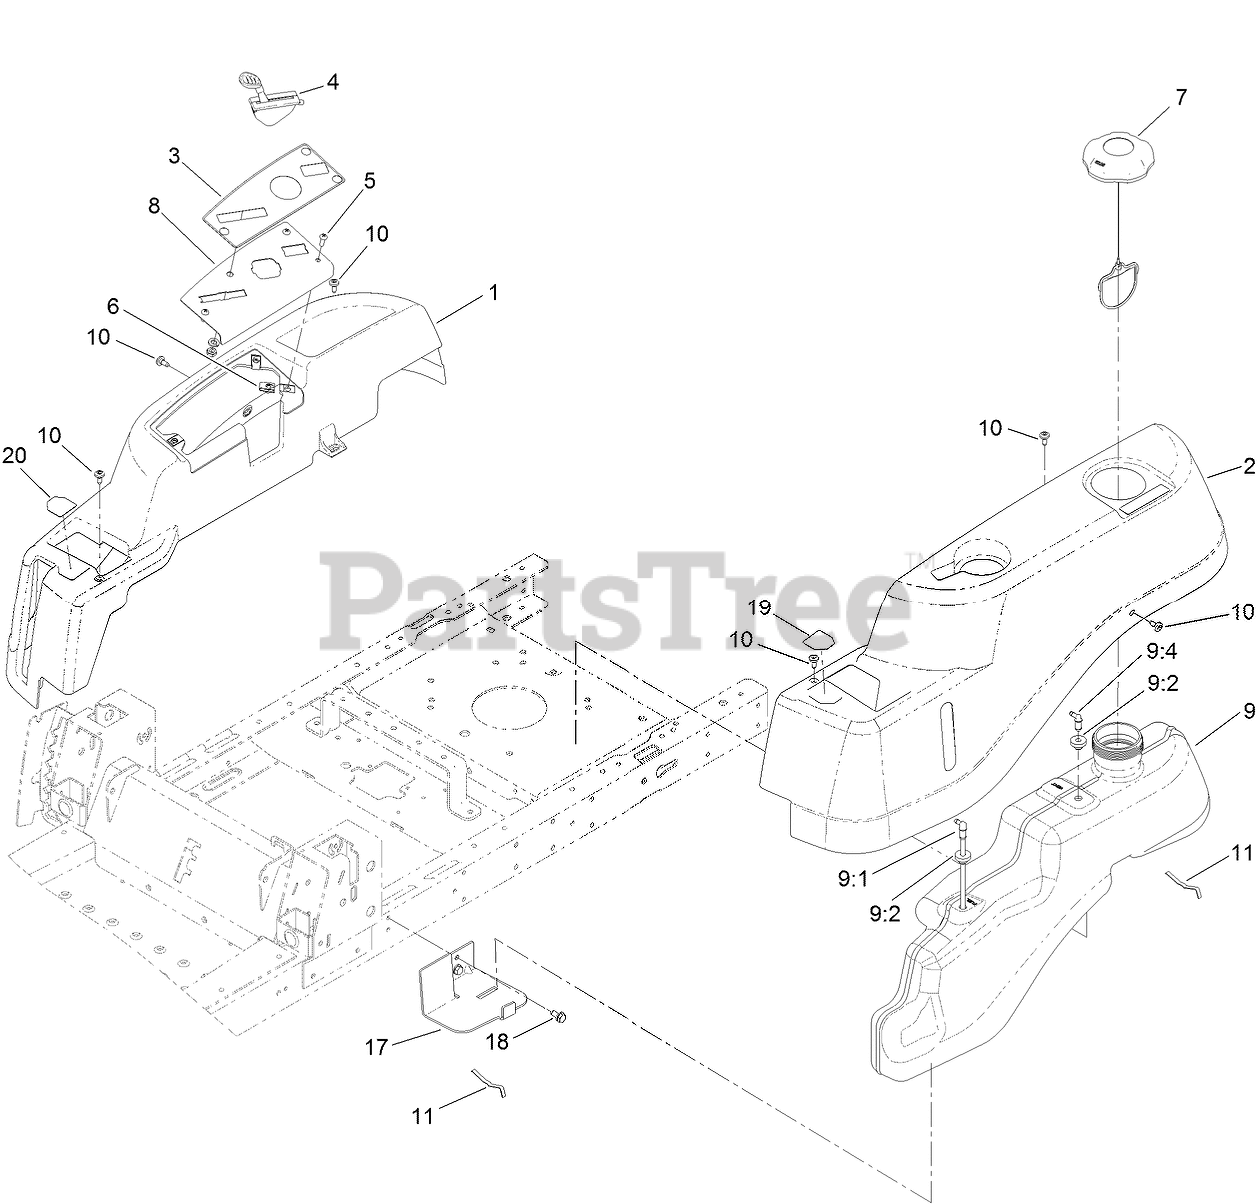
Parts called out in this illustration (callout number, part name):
1	POD-RH
2	POD-LH
3	DECAL-PANEL, CONTROL
4	CABLE-THROTTLE
5	SCREW-PRH
7	CAP-FUEL, RATCHETING
8	PLATE-CONTROL
9	FUEL TANK ASM
9:1	CONNECTOR-ELBOW, 90 DEG
9:2	BUSHING
9:4	FITTING-PLASTIC
10	SCREW-SHOULDER
11	SPRING
17	SUPPORT-TANK, FRONT
18	SCREW-HWHTF
19	DECAL-CONTROL LEVER, LH
20	DECAL-CONTROL LEVER, RH
